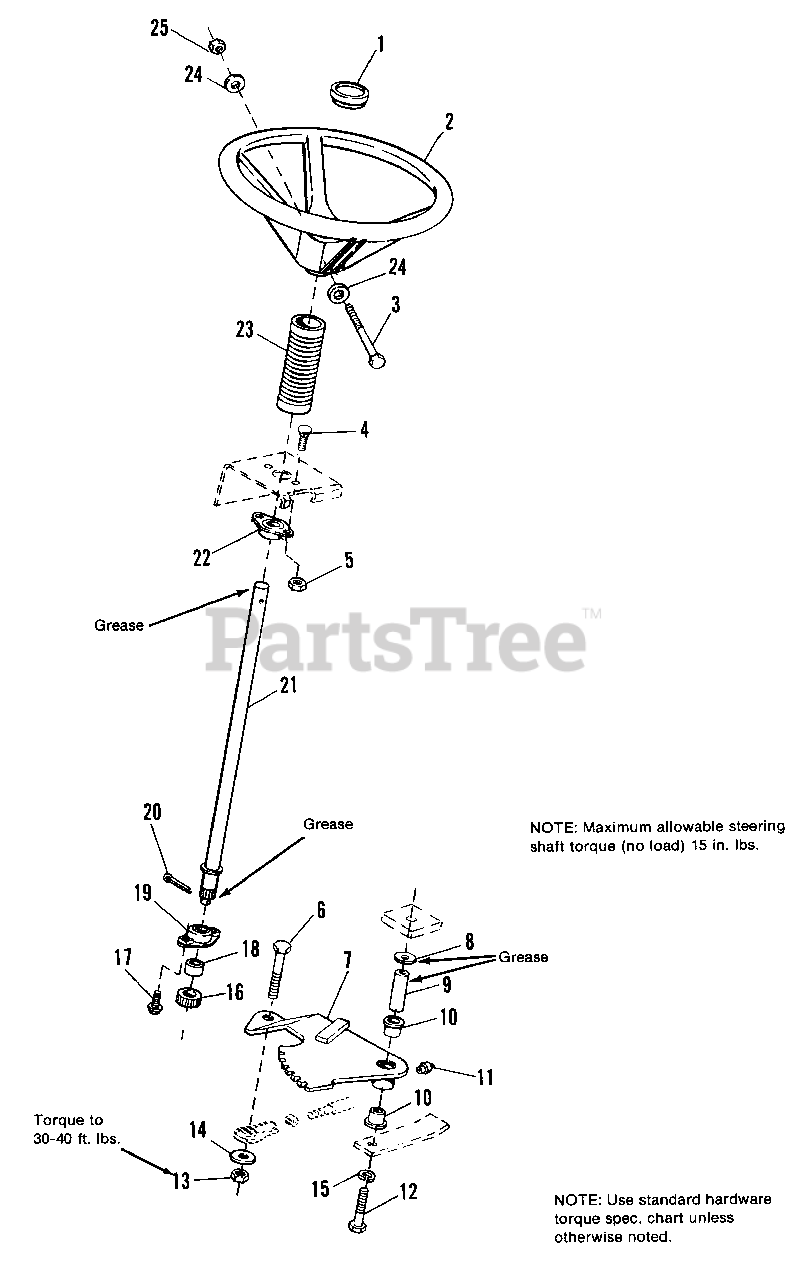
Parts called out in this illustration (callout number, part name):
1	CAP, Steering Wheel
2	STEERING WHEEL
3	CAPSCREW, Hex, 5/16-18 x 3-1/2
4	CARRIAGE BOLT, 5/16-18 x 3/4
5	NUT, Hex, Whizlock, 5/16 x 18
6	CAPSCREW, Hex, 1/2-13 x 1-1/2
7	ARM ASSY.
8	WASHER, Nylon
11	FITTING, Lube
12	CAPSCREW, Hex, 1/2-13 x 2-1/4
13	NUT, Esna Hex, 1/2-13 (Thin)
14	WASHER, 1/2 x 1
15	LOCKWASHER, 1/2
16	PINION, Steering Shaft
17	SCREW, Whizlock, 3/8-16 x 3/4
18	SPACER, Steering Shaft
19	BEARING, Flange
20	PIN, Cotter
21	SHAFT ASSY., Steering
22	BEARING, Flange
23	TUBE, Steering Shaft
24	WASHER, 5/16
25	NUT, Hex Esna Lock, 5/16-18
